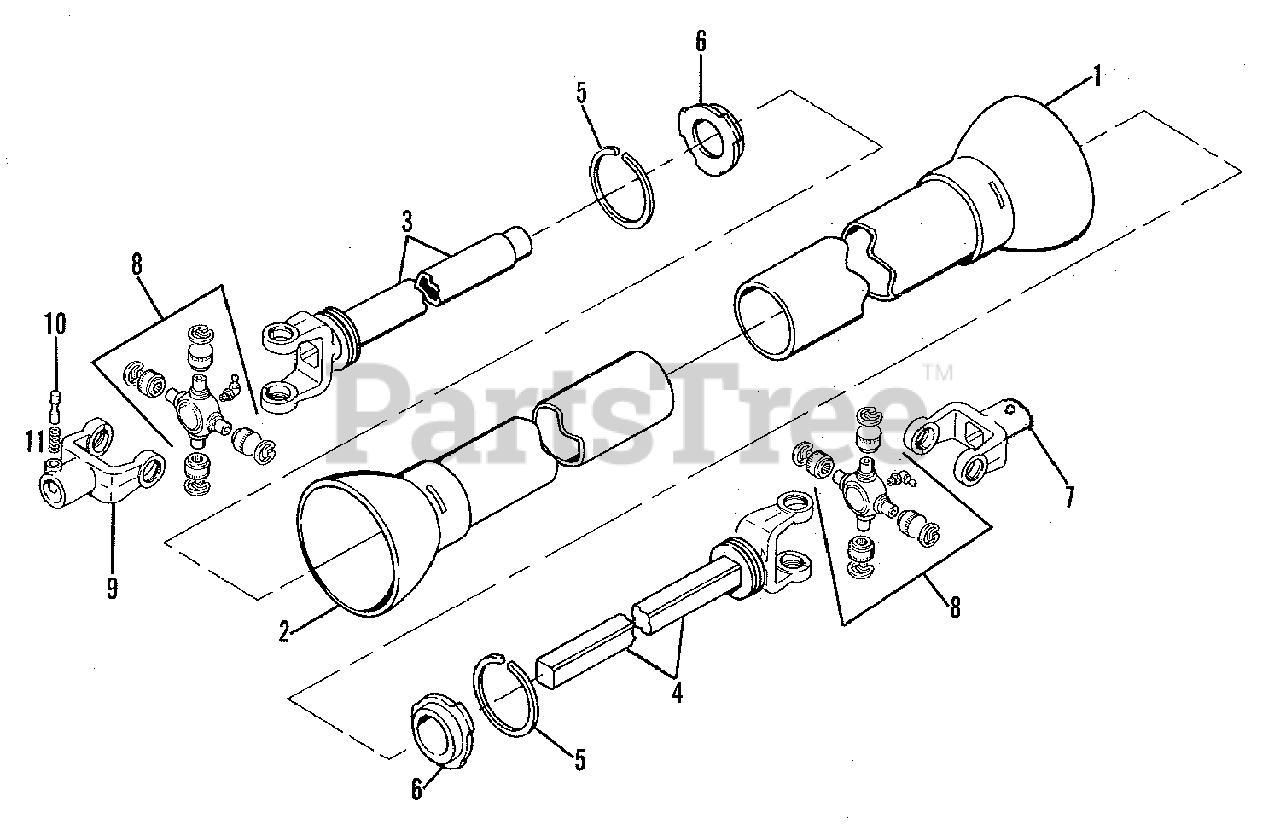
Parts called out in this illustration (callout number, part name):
1	SHIELD ASSEMBLY, Outer
2	SHIELD ASSEMBLY, Inner
3	TUBE & YOKE ASSEMBLY
4	SHAFT & YOKE ASSEMBLY
5	BEARING, Support
6	SLEEVE, Bearing
7	YOKE (Gearbox End)
8	U-JOINT KIT, Yoke
9	YOKE (Tractor End)
10	PIN, Quick, Lock
11	SPRING, Pin
12	WASHER, Retaining
